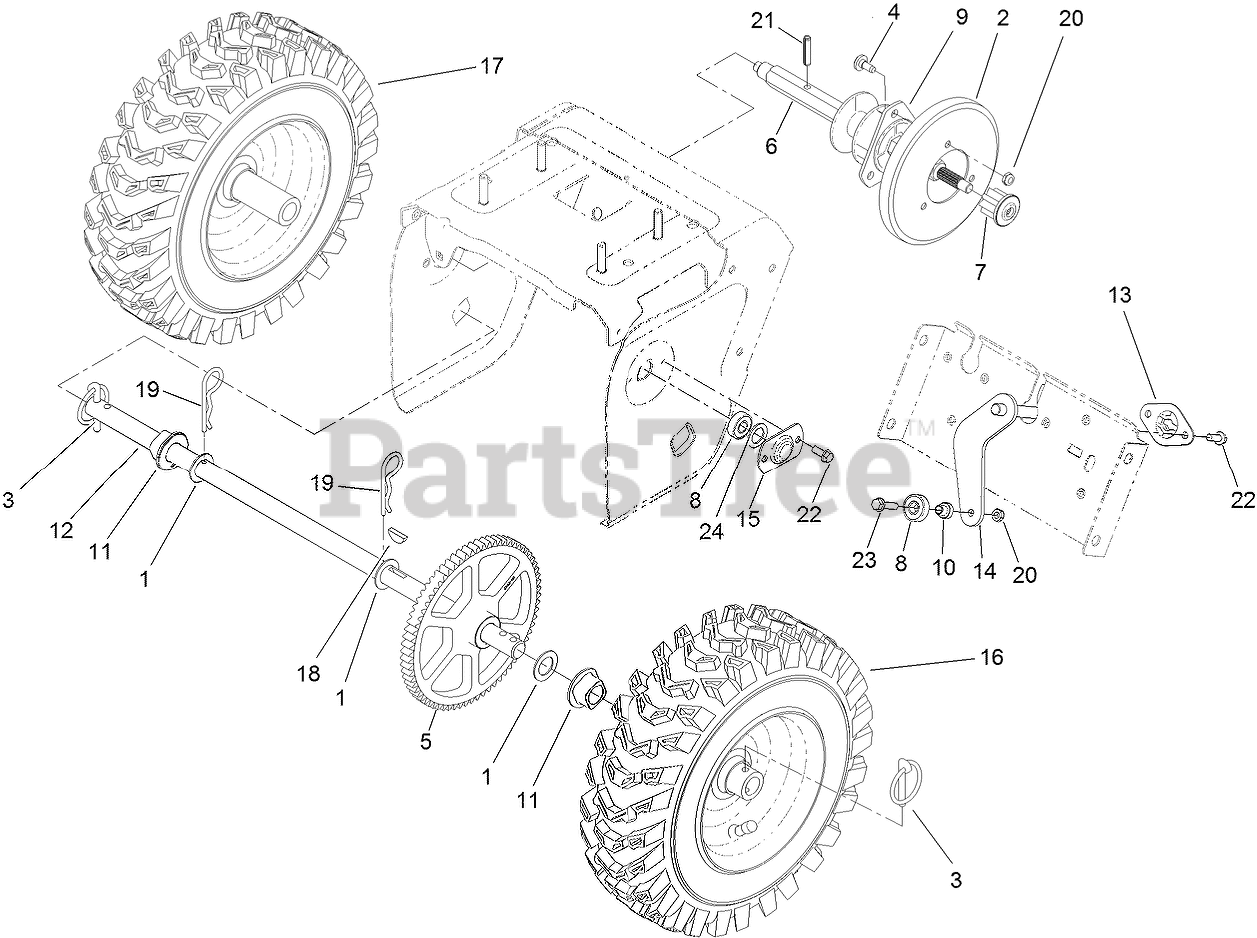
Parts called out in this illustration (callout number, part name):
1	WASHER-THRUST
2	WHEEL-FRICTION
3	KLIK PIN ASM
4	SCREW-SHOULDER
5	GEAR-AXLE
6	SHAFT-HEX
7	GEAR-PINION, 8 TOOTH
8	BEARING-BALL
9	TRUNNION
10	SPACER-PLATE, SHIFT
11	BUSHING-AXLE
13	RETAINER-PLATE, SHIFT
14	SHIFT PLATE ASM
15	RETAINER-BEARING
16	LH WHEEL AND TIRE ASM
17	RH WHEEL AND TIRE ASM
18	KEY-WOODRUFF
19	PIN-HAIR
20	NUT-LOCK, NI
21	PIN-ROLL, SLOTTED
22	SCREW-HWH
23	SCREW-HWHTF
24	WASHER-RUBBER
